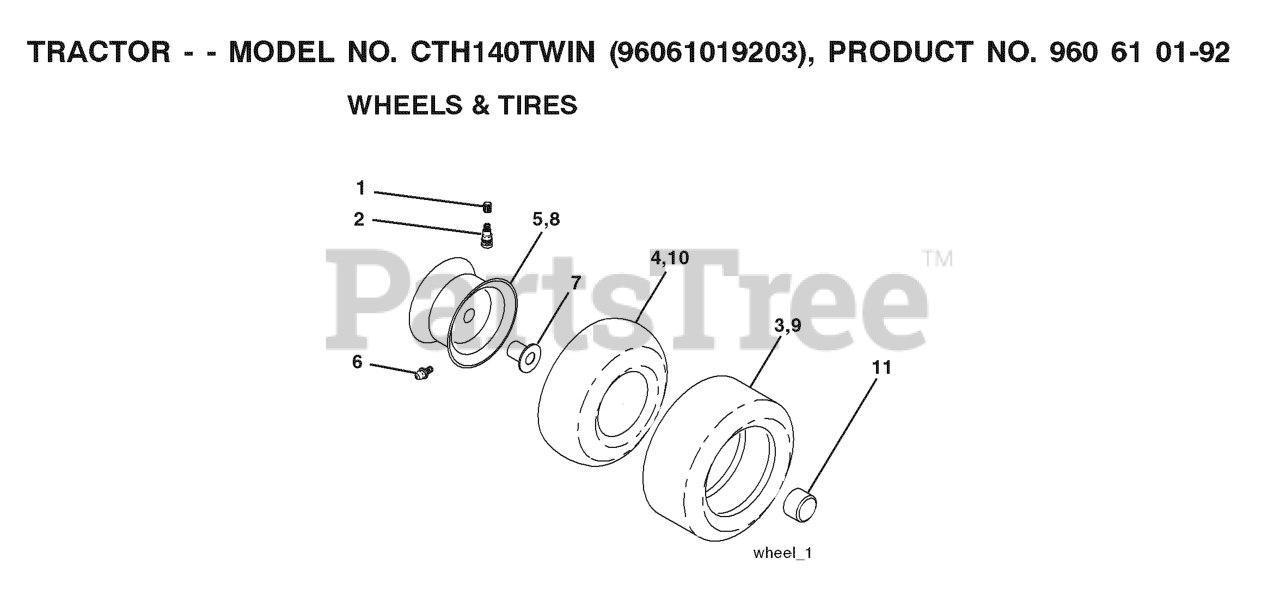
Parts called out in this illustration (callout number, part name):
2	VALVE STEM LT
3	TIRE HEAVY DUTY
4	TUBE.5.3/4.5/6
5	RIM ASM 6" FRONT SILVER
6	FITTING LT
7	BEARING T
8	RIM ASM 8" REAR SILVER
9	TIRE.TS.20X10-8
10	TUBE
11	CAP, AXLE BLK
